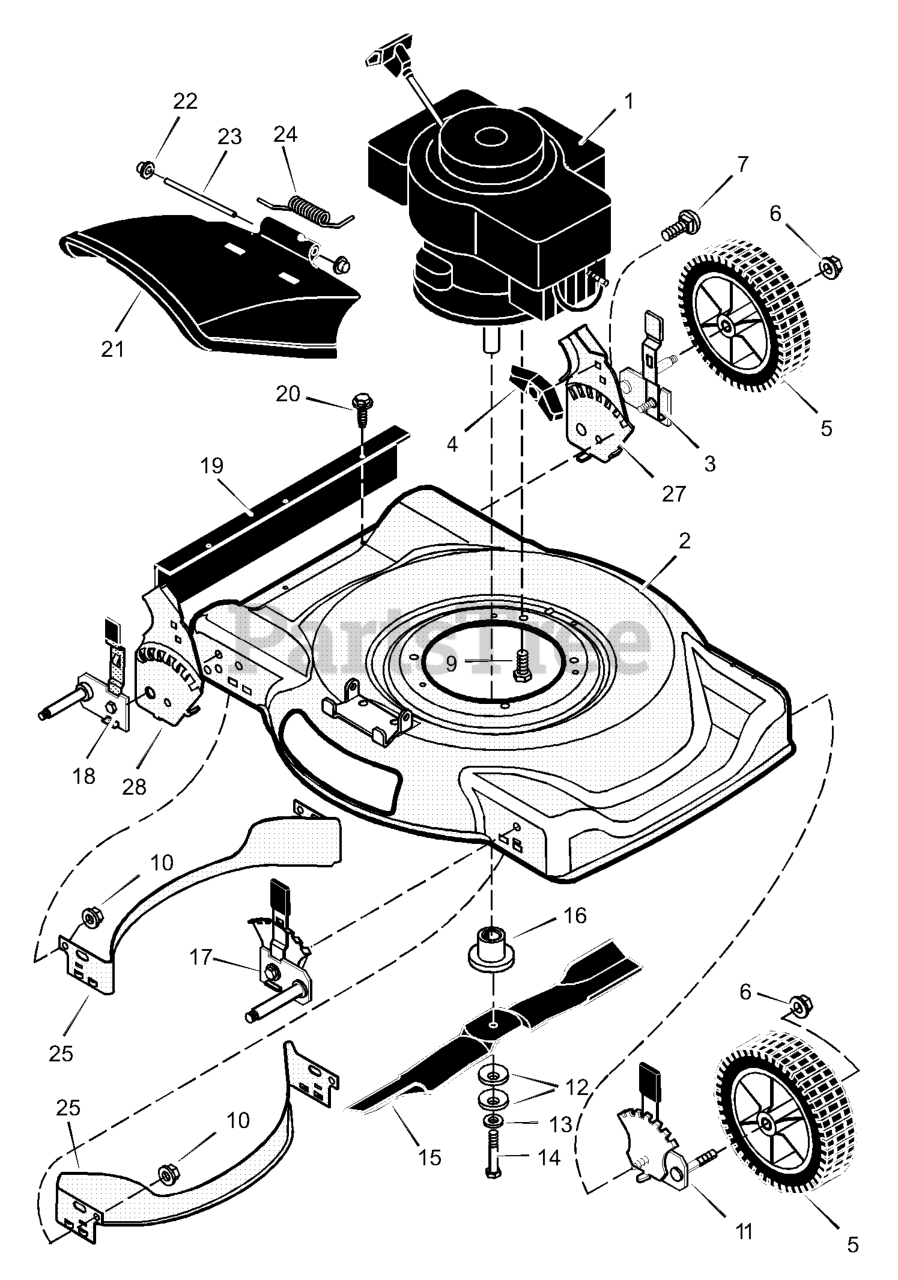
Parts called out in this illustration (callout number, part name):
1	Engine
2	Housing
3	Height Adjuster, Left Rear
5	Wheel & Tire
6	Locknut, Flange
7	Bolt. Carriage
9	Bolt, Engine
10	Nut
11	Height Adjuster, Left Front
12	Washer, Bellevlle
14	Bolt, Hex
16	Adapter, Blade
17	Height Adjuster, Right Front
18	Height Adjuster, Right Rear
19	Guard, Rear
21	Deflector, Rear
22	Push-on-Cap
23	Pin, Pivot
27	Bracket, Left Handle
28	Bracket, Right Handle
